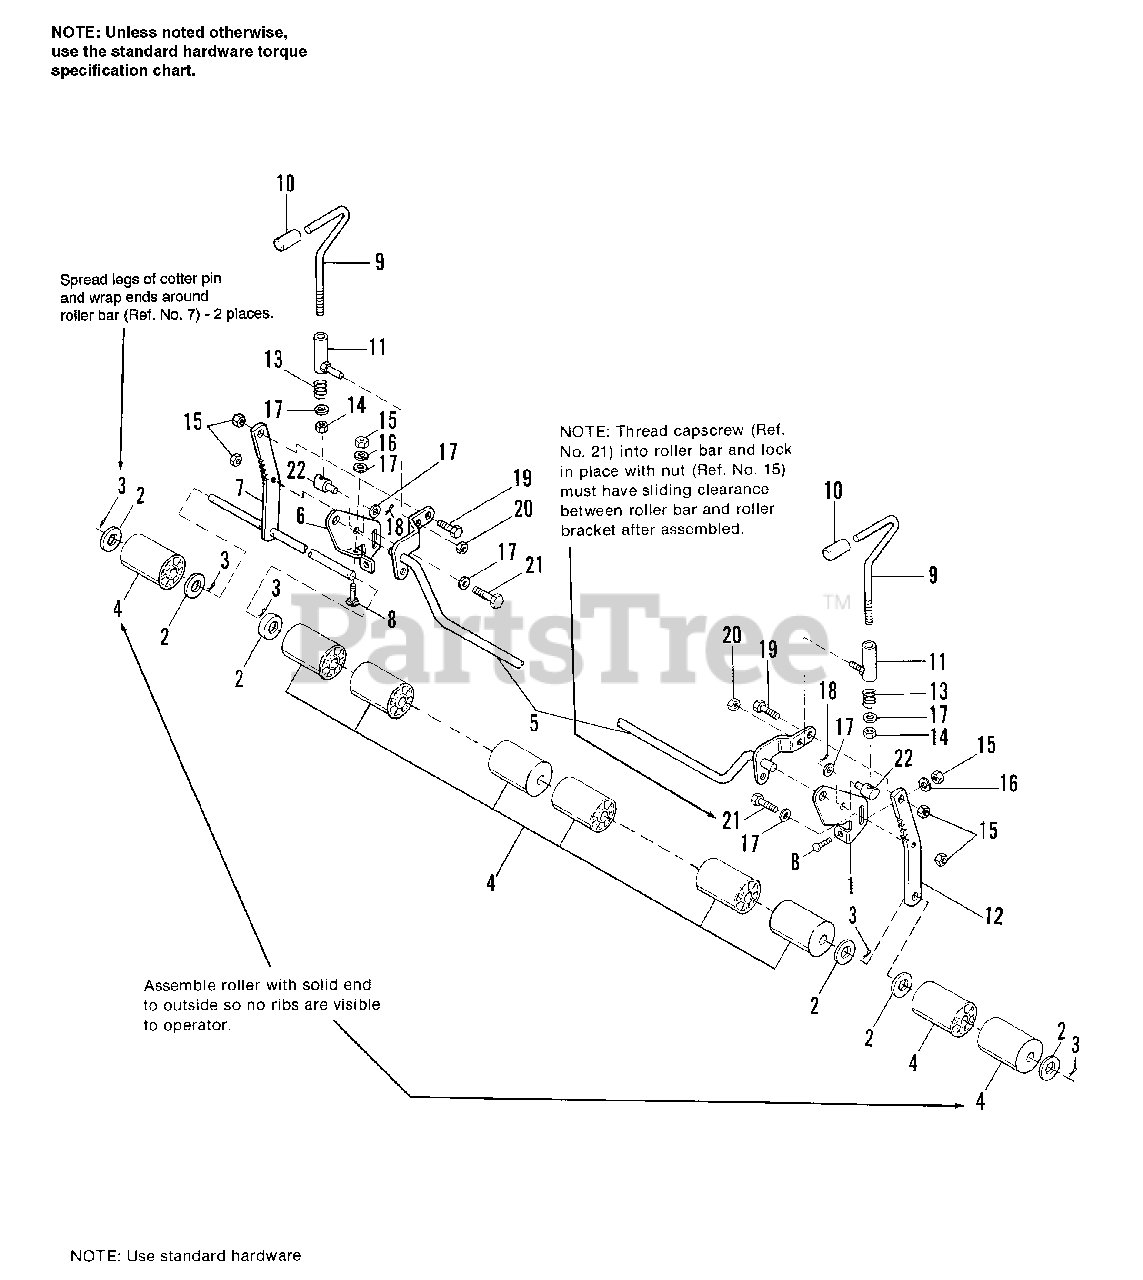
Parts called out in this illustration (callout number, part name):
1	BRACKET, Roller, L.H.
2	WASHER, Plain, 5/8
3	PIN, Cotter, 3/16 x 1
5	ROCKER ARM ASSEMBLY
6	BRACKET, Roller, R.H.
7	SHAFT ASSEMBLY, Roller
8	CARRIAGE BOLT, 3/8-16 x 1
9	HANDLE, Adjusting
10	GRIP
11	SOCKET ASSEMBLY
12	BAR, Roller
14	NUT, Hex, Jam, 3/8-16
15	NUT, Hex, Full, 3/8-16
16	LOCKWASHER, 3/8
17	WASHER, 3/8
18	PIN, Cotter, 3/32 x 3/4
19	CAPSCREW, Hex Hd, 3/8-16 x 1
20	LOCKNUT, Hex, Full, 3/8-16
21	CAPSCREW, Hex Hd, 3/8-16 x 1-1/4
